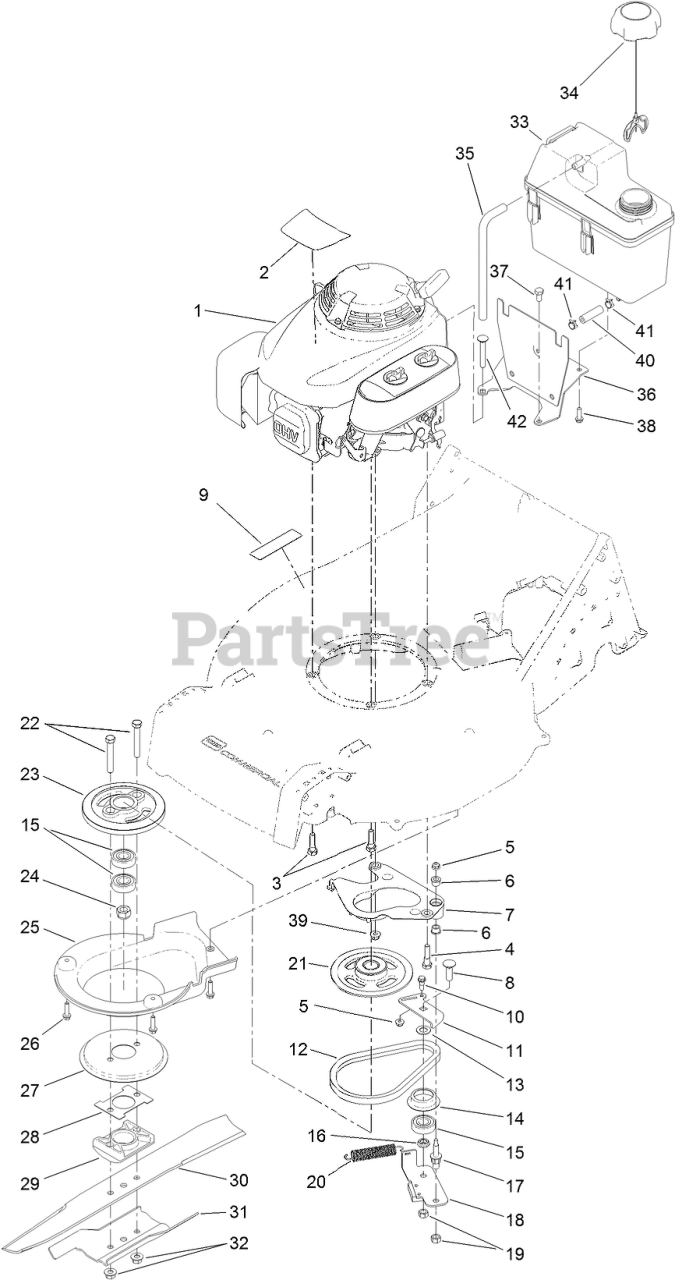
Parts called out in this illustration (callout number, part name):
1	ENGINE-HONDA, GXV160 GAS
2	DECAL-ENGINE, HONDA
3	SCREW-HHSH
4	SCREW-SHOULDER
5	NUT-HF
6	BUSHING-FLANGE
7	PLATE-ANCHOR
8	BOLT-CARR
9	DECAL-ARRESTER, SPARK
10	BOLT-SHOULDER
11	PLATE-GUIDE, BBC
12	BELT
13	WASHER-PLAIN
14	RETAINER-BELT
15	BEARING-BALL
16	SPACER-BEARING
17	BOLT-SHOULDER
18	PLATE-BRAKE
19	NUT-HEX
20	SPRING-TENSION, BRAKE
21	PULLEY
22	SCREW-HH
23	DRUM
24	NUT-HEX
26	SCREW-HWHTF
27	DISC
28	SPACER-DRIVER, BLADE
29	SUPPORT-BLADE
30	BLADE-RECYCLING
31	ACCELERATOR-BLADE
32	NUT-FLANGE, LOCK
33	TANK-FUEL
34	CAP-FUEL
35	HOSE-VENT, CANISTER
36	MOUNT-TANK
37	SCREW-HH
38	SCREW-HWH
39	NUT-HF, NI
40	HOSE-FUEL
41	CLAMP-HOSE
42	BOLT-CARR
